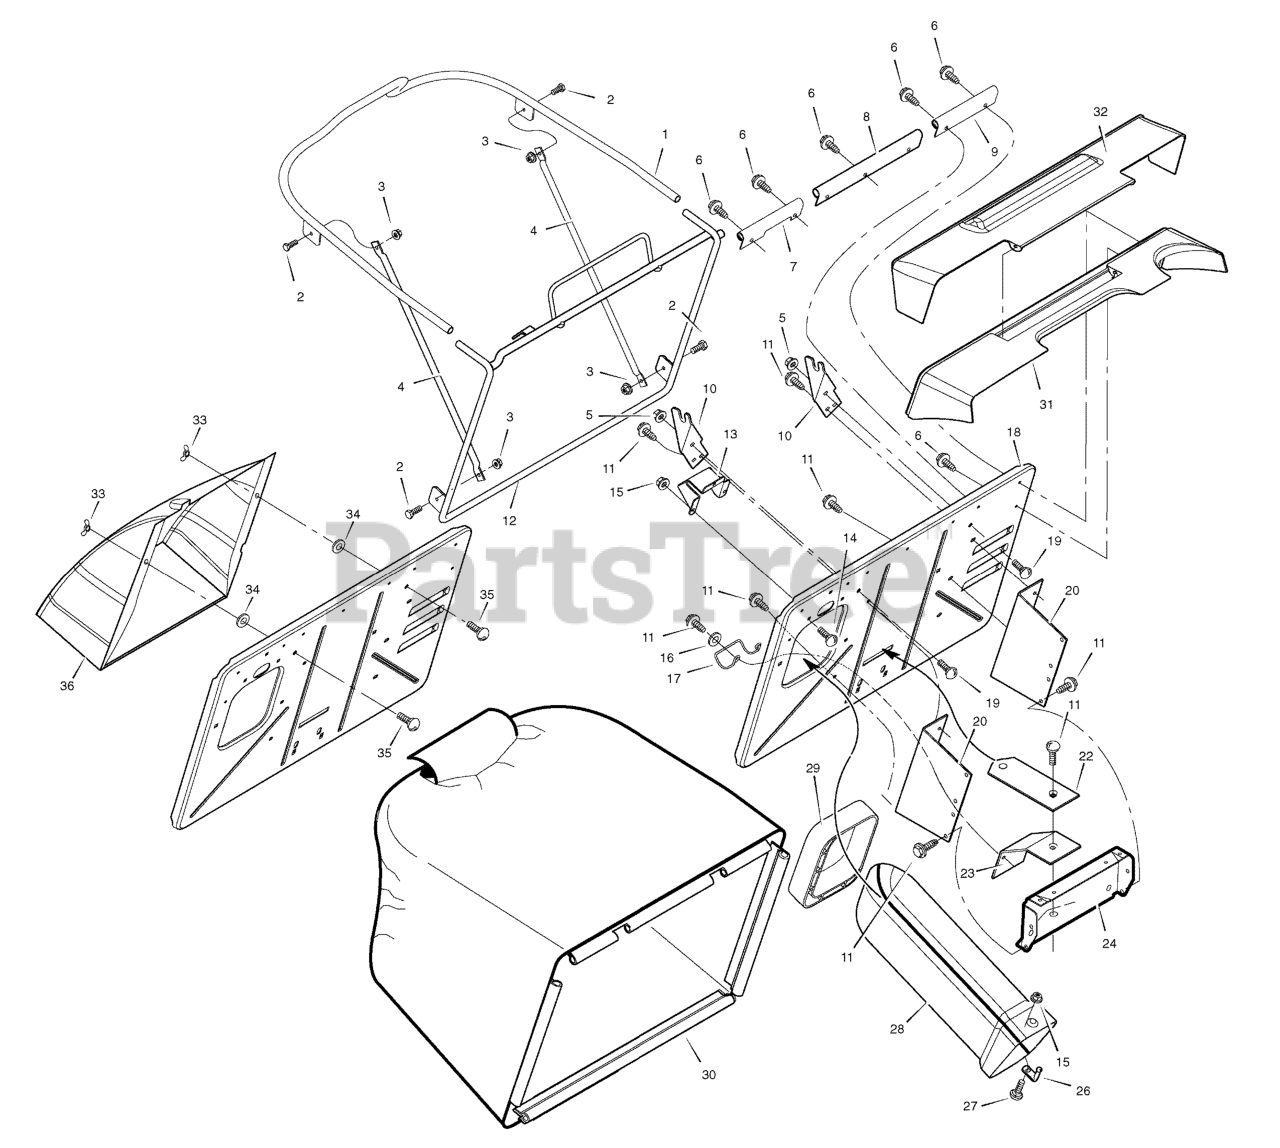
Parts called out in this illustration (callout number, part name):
1	TUBE, Top
4	STRUT, Bag
5	NUT, Flange
6	FASTENER, Panel
7	SEAL, Bag (Right End)
8	SEAL, Bag (Center)
9	SEAL, Bag (Left End)
12	ASSEMBLY, Bag Frame
13	BRACKET, Switch
14	BOLT, Carriage
15	NUT, Flange
17	LATCH, Spring
18	PANEL, Rear
19	BOLT, Carriage
20	BRACKET, Bagger Mounting
22	PLATE, Hitch
23	BRACKET, Lower Mounting
24	PLATE, Hitch
26	PIN, Latch
27	BOLT, Carriage
28	TUBE, Connecting
29	GROMMET, Extension Tube
30	BAG, Grass
31	BAGGER COVER, Front
32	BAGGER COVER, Rear
34	SPEED NUT
35	BOLT, Carriage
36	DEFLECTOR, 30" RD
37	DEFLECTOR KIT
